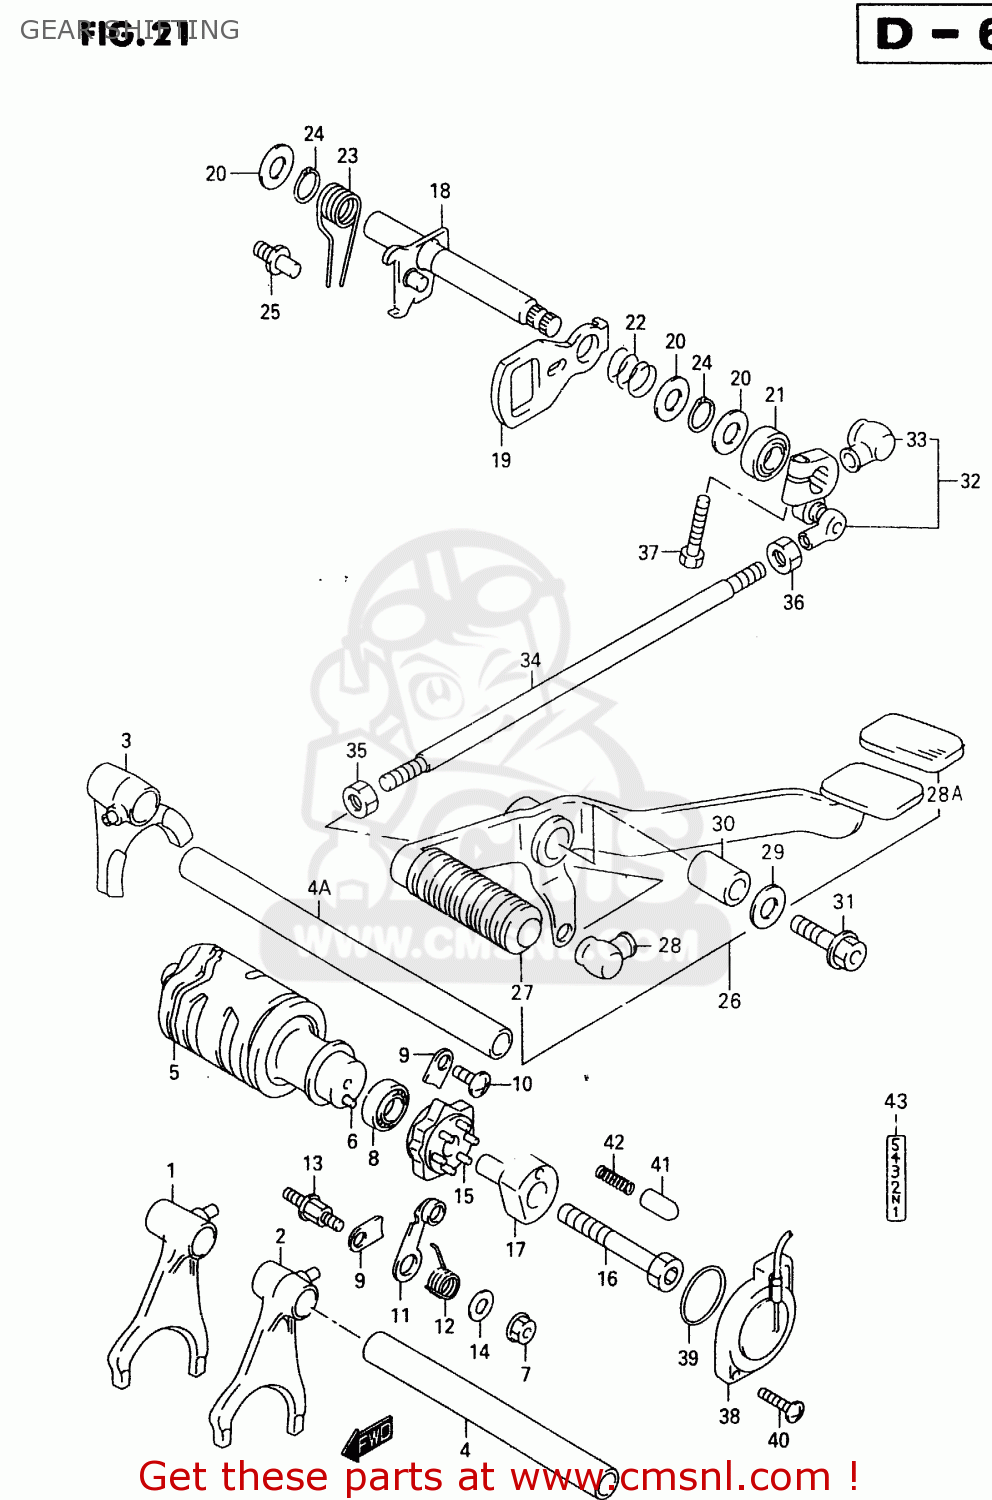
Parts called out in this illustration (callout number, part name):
1	FORK,GEAR SHIFT NO.1
2	FORK,GEAR SHIFT NO.2
3	FORK,GEAR SHIFT NO.3
4	SHAFT,GEAR SHIFT FORK NO.1
4A	SHAFT GEAR SHIFT FORK NO.2
5	CAM,GEAR SHIFT
6	PIN
7	NUT
8	BEARING(25X47X8)
9	RETAINER,BEARING
10	SCREW
11	STOPPER,GEAR SHIFT CAM
12	SPRING,SHIFT CAM STOPPER
13	SUPPORT,CAM STOPPER ARM
14	WASHER
15	PLATE,GEAR SHIFT CAM
16	BOLT
17	HOLDER,NEUTRAL SWITCH
18	SHAFT,GEAR SHIFT
19	PLATE,GEAR SHIFT CAM DRIVE
20	SHIM(14X22X1)
21	SEAL,OIL(14X22X6)
22	SPRING
23	SPRING
24	CIRCLIP
25	STOPPER,GEAR SHIFT CAM
26	LEVER ASSEMBLY,GEAR SHIFTING
27	RUBBER
28	COVER,DUST
28A	RUBBER,BRAKE PEDAL
29	WASHER (10.5X24X2.3)
30	SPSCER,GEAR SHIFT LEVER
31	BOLT(10X40)
32	ARM,GEAR SHIFT LINK
33	COVER,DUST
34	ROD,GEAR SHIFT LINK
35	NUT
36	NUT 6MM
37	BOLT
38	BASE ASSY,GEAR SHIFT TERMINAL
39	O RING(D:2.4,ID:35.5)
40	SCREW
41	PIN
42	SPRING
43	LABEL,GEAR SHIFT
